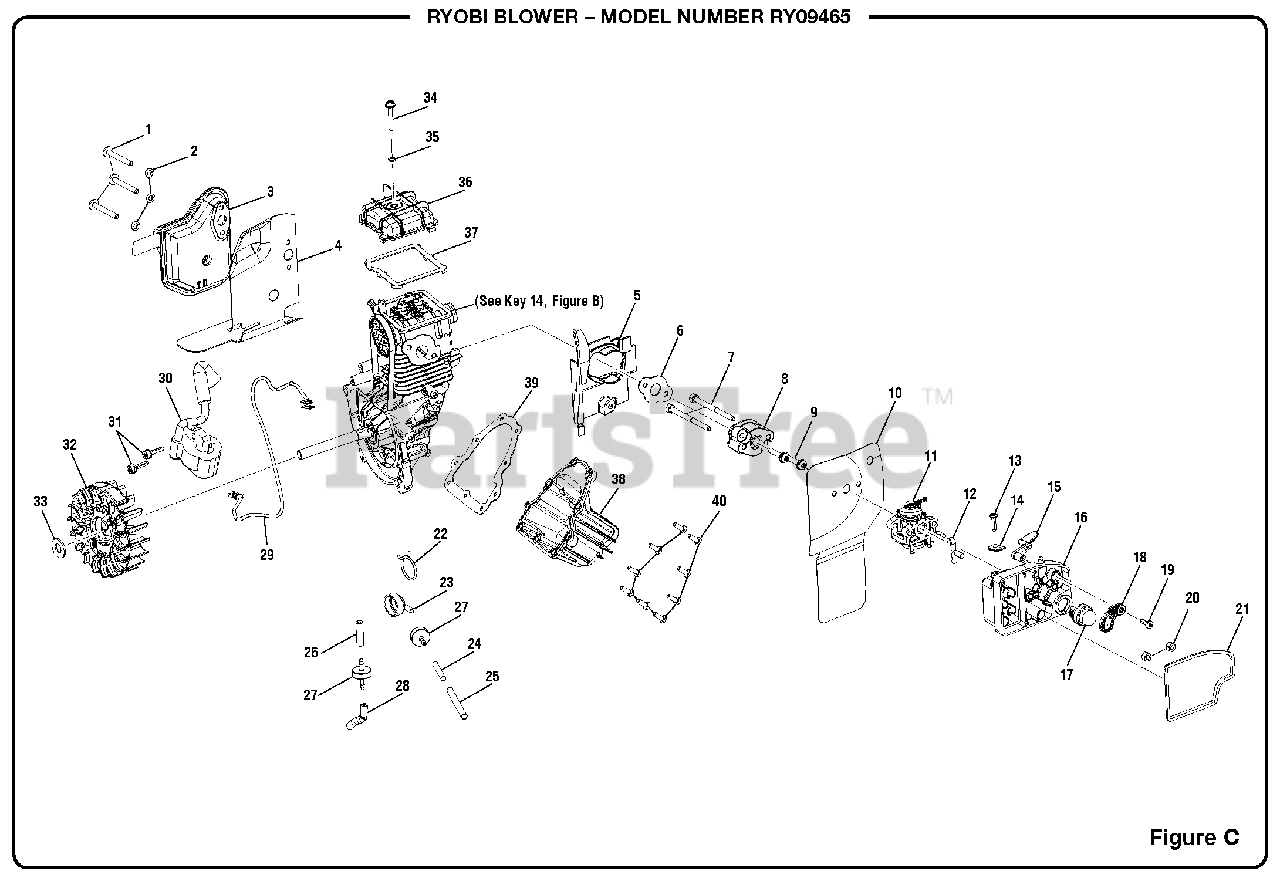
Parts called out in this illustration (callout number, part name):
1	Screw (M5 x 42 mm)
2	Lock Washer (M5)
4	Muffler Gasket
5	Air Baffle
6	Heat Gasket
7	Bolt (M5 x 63 mm)
9	Screw (M5 x 23 mm)
11	Carburetor
12	Tubing (54 mm)
13	Screw (M4 x 16 mm)
15	Choke Lever
16	Air Box Base
17	Primer
18	Choke Plate
19	Screw (M4 x 12 mm)
20	Lock Nut (M5)
21	Air Box Seal
23	Breather Fitting
24	Tubing (70 mm)
25	Shield Sleeve
26	Tubing (42 mm)
27	Check Valve
28	Tubing (25 mm)
29	Lead Assembly
30	Ignition Module
31	Screw (M4 x 19 mm)
32	Flywheel Assembly
33	Washer
34	Screw (M4 x 27 mm)
36	Cam Cover
40	Screw (M4 x 12 mm)
